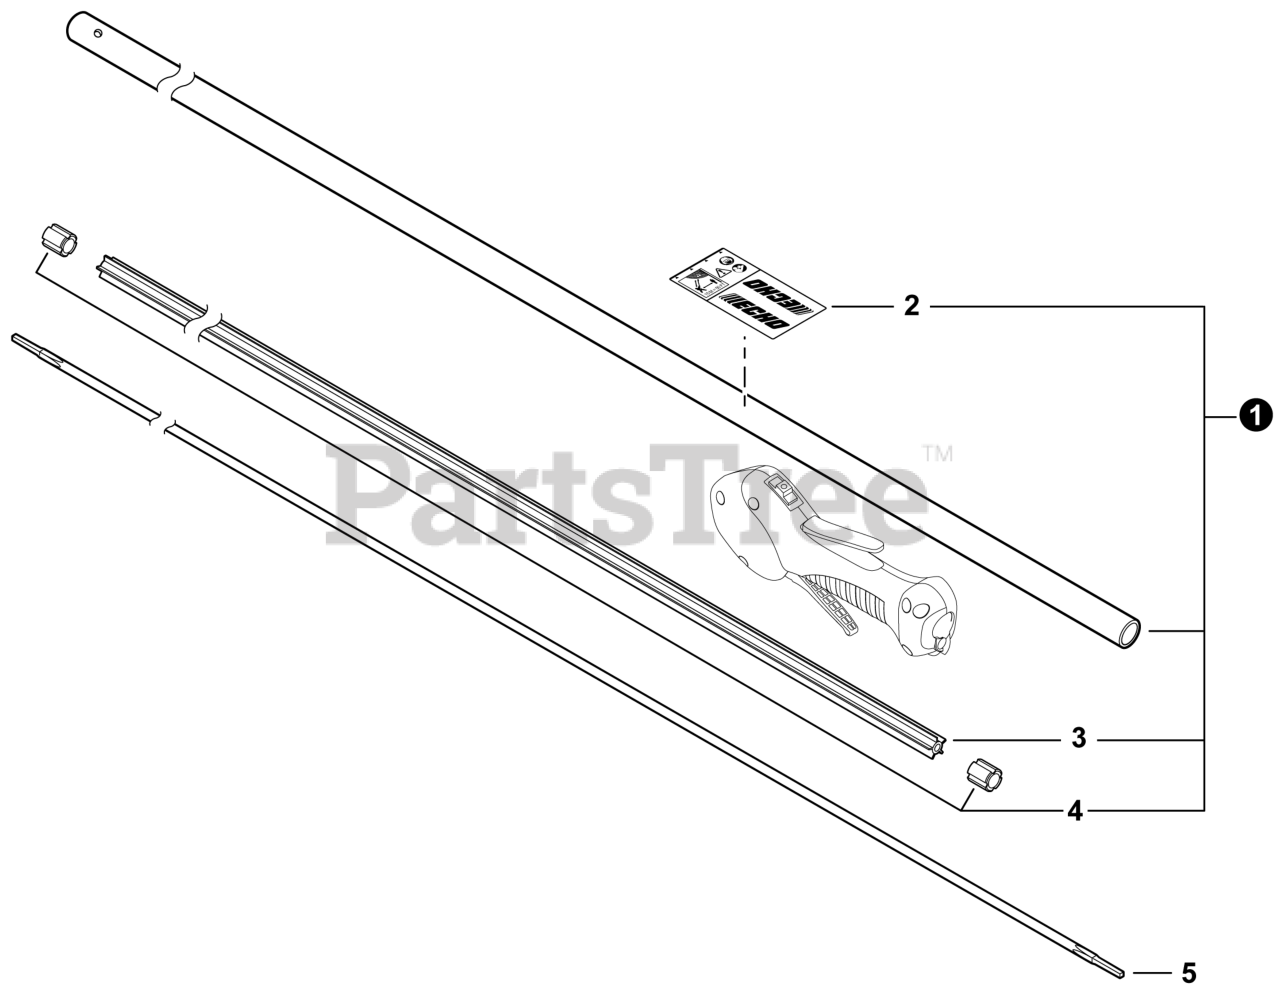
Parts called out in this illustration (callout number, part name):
1	MAIN PIPE ASSY
2	LABEL - CAUTION
3	LINER - FLEXIBLE
5	DRIVESHAFT - FLEXIBLE
